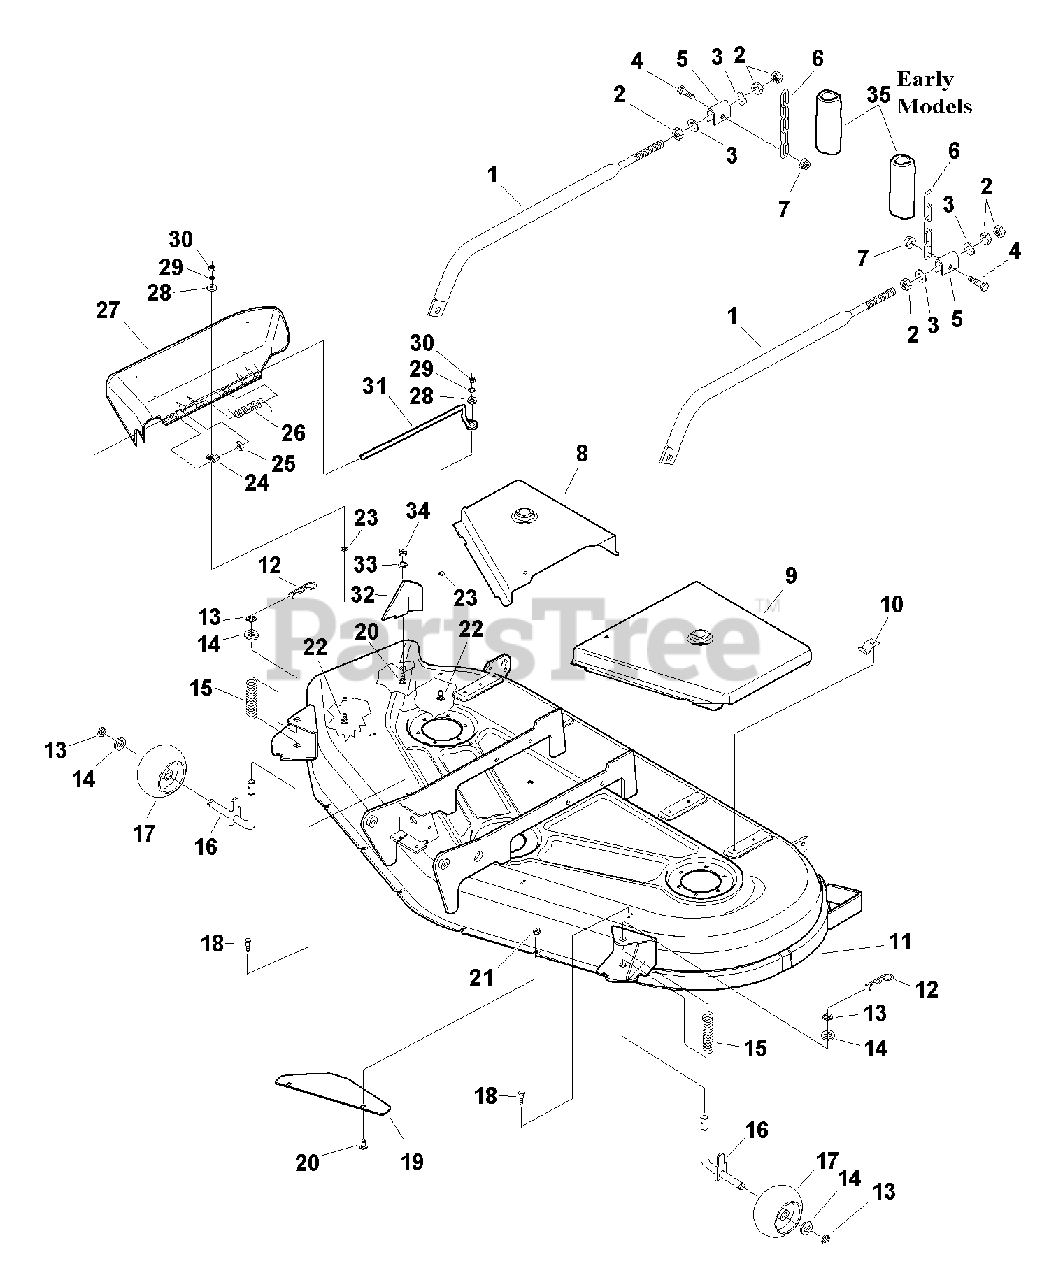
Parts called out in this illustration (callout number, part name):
1	ARM, Adjusting
2	NUT, Hex, Jam, 5/8-18
3	WASHER, 5/8
4	BOLT, Wheel
5	TRUNNION
6	CHAIN, 6 Link
7	NUT, Hex, Flange Lock, 3/8-16
8	COVER, Arbor, RH (Orange)
8	COVER, Arbor, RH (Solar Black)
9	COVER, Arbor, LH (Orange)
9	COVER, Arbor, LH (Solar Black)
10	CLIP, Spring
11	HOUSING, 54" Mower Deck (Orange)
11	HOUSING, 54" Mower Deck (Red)
11	HOUSING, 54" Mower Deck (Solar Black)
12	CLIP, Hairpin
13	KLIPRING, 5/8
14	WASHER, Plain, 5/8
15	SPRING, Compression
16	ASSEMBLY, Spindle and Stop
17	WHEEL, Gauge
18	CAPSCREW, Taptite, 1/4-20 x 3/8
19	BAFFLE, Front, Anti-blowout (S/N 1-59999)
20	CARRIAGE BOLT, 5/16-18 x 3/4 (1 needed for discharge baffle)
21	NUT, Hex, Nylon Lock, 5/16-18
22	CARRIAGE BOLT, 1/4-20 x 7/8
23	NUT, Push
24	CAP, Spring End .093 ID
25	WASHER, Plain, 5/16
27	DEFLECTOR, Plastic
28	WASHER, Plain, 1/4
29	LOCKWASHER, 1/4
30	NUT, 1/4-20
31	ROD, Deflector, Front
32	BAFFLE, Discharge (S/N 60000 and above)
33	LOCKWASHER, 5/16 (S/N 60000 and above)
34	NUT, Hex, 5/16-18 (S/N 60000 and above)
35	TUBE, Shrink Wrap (Early Models)
